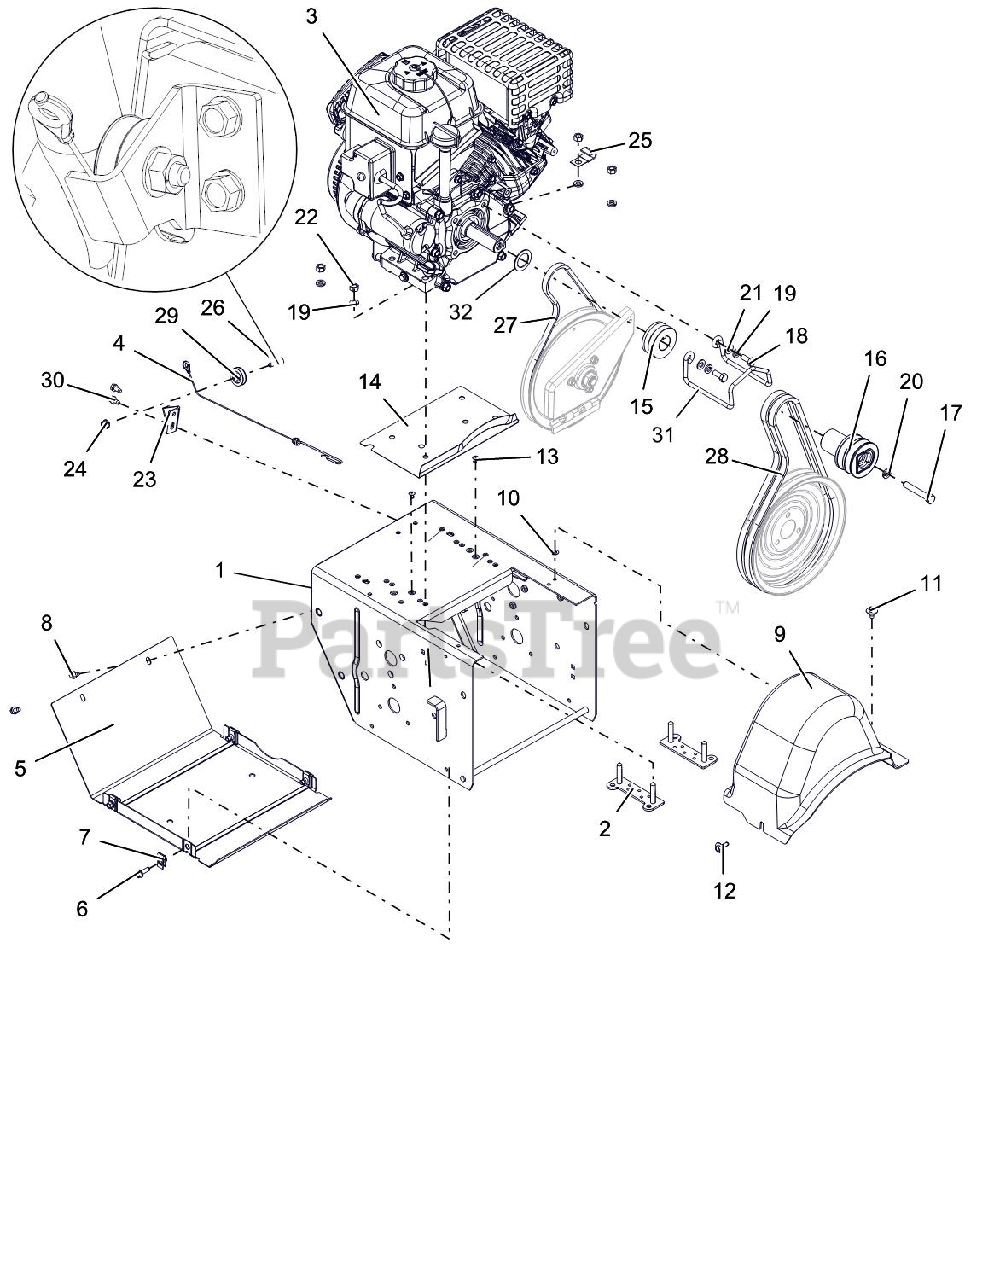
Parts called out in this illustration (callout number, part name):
1	FRAME, MAIN-DELUXE(WELDMENT)
2	STRAP, BOLT - SMALL ENGINE
3	ENGINE, ARIENS AX254 240V/60W
4	CABLE, LOWER TRACTION,SS & PRO
5	COVER, BOTTOM
6	BLT-HEX .25-20X.75 HWH YZ GR5
7	NUT-RTNR .25-20X.56
8	SCR-TAP .25-20X.50 HWH TR YWZ
9	COVER, BELT-SMALL
10	NUT-PUSH .25X.50 O.D.
11	SCR-TAP .25-20X.50 LGHWH TR YZ
12	SCR-TAP .25-20X.5 CAPTIVE
13	RVT-POP .187 YZ
14	BAFFLE, WATER-SMALL
15	SHEAVE, DRIVE
16	SHEAVE, ATTACHMENT 2-GRV
17	BLT-HEX .38-24X2.25 YWZC GR5
18	BLT-HEX .31-24X.75 YWZC GR5
19	WSHR-LK .312X.097 HVY YWZC
20	@WSHR-LK .38X.094 REG YWZC
21	@WSHR-FL-STL.344X.688X.065YWZC
22	@NUT-HEX .31-18 YWZC
23	BRACKET, CABLE PULLEY
24	@NUT-LK-TOP-FLG .25-20 YWZC
25	J-CLAMP
26	BOLT, SHLDR-.375X.375X.25-20
27	V-BELT, 3L-WRAPPED
28	V-BELT, HA-RAW EDGE (SET)
29	PULLEY, CABLE
30	SCR-TAP .25-20X.50 HWH TR YWZ
31	FINGER, BELT
32	WSHR-FL-STL 1.010X1.505X.062YZ
